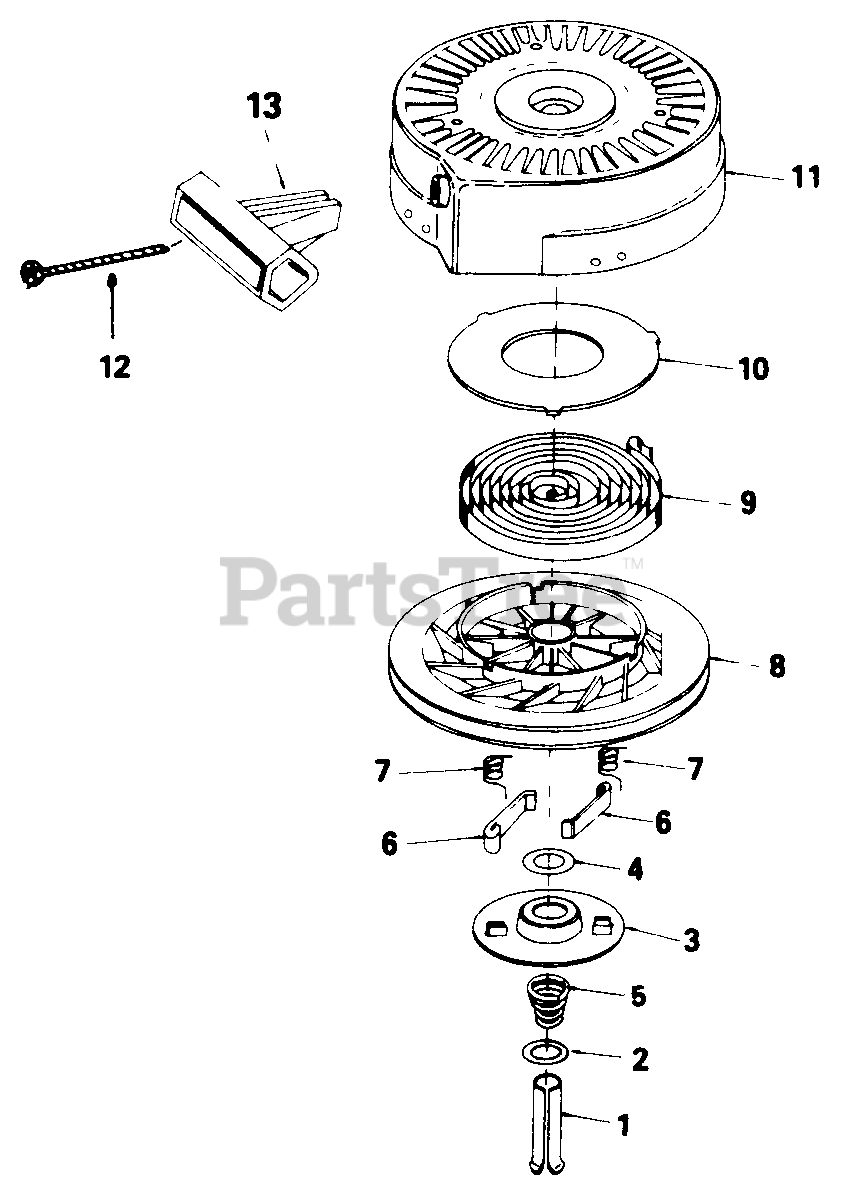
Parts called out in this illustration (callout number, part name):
1	Pin, Spring
5	Spring, Brake
6	Dog, Starter
7	Spring, Dog
8	Pulley
9	Spring, Rewind
10	Cover, Spring
11	Housing Ass'y., Starter
12	Rope, Starter
13	Handle, Starter
